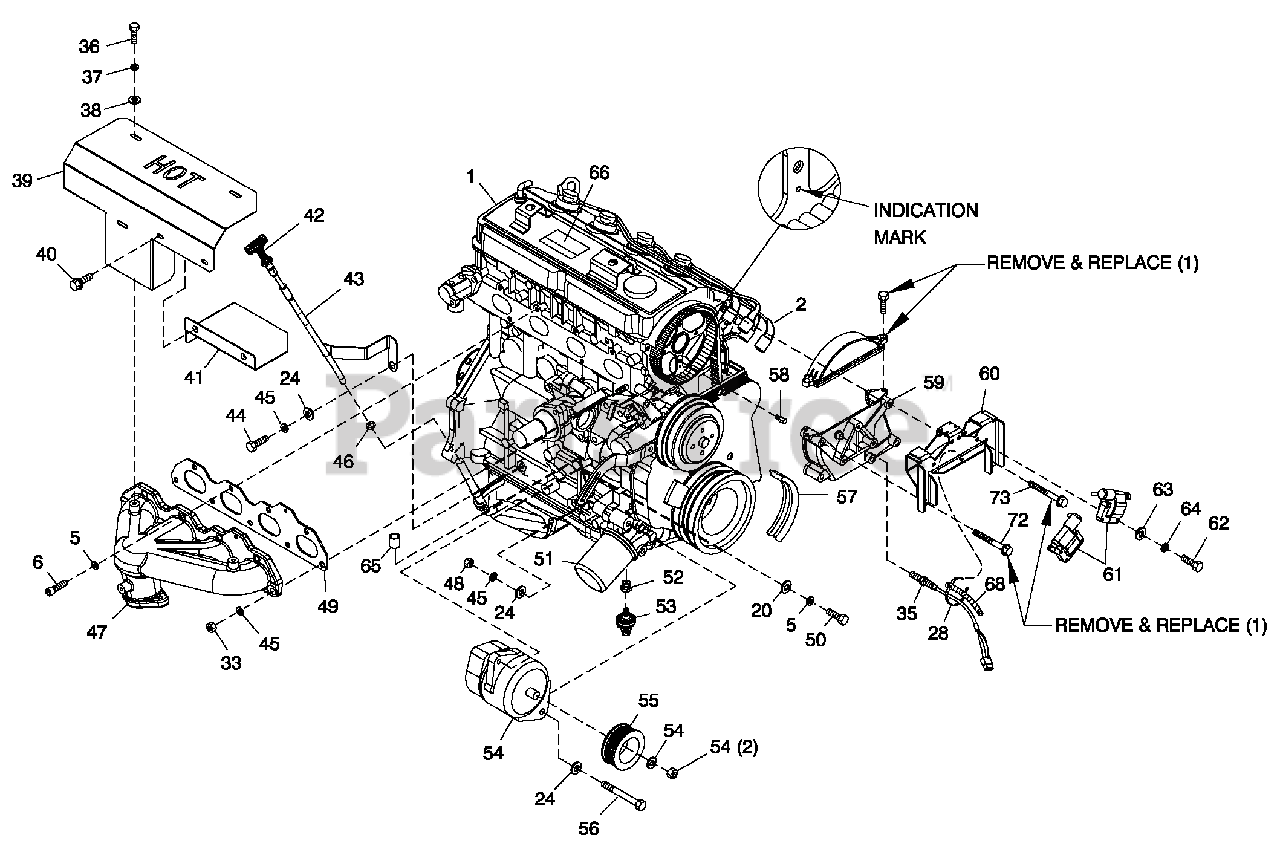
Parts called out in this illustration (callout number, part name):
1	ENGINE 2.4L G2
2	SPARK PLUG WIRE SET 2.4L G2 IG
5	WASHER LOCK M8-5/16
6	SCREW SHC M8-1.25 X 25 C12.9
7	SWITCH HI-TEMP 245D X 3/8 NPT
20	WASHER FLAT 5/16-M8 ZINC
24	WASHER FLAT 3/8-M10 ZINC
28	TIE WRAP UL 7.4"X .19" BLK
33	NUT HEX M10-1.25 G8 YEL CHR
35	ASSY MAGPICKUP(3/8-24 MALE)
36	SCREW HHC M6-1.0 X 12 G8.8
37	WASHER LOCK M6-1/4
38	WASHER FLAT 1/4-M6 ZINC
39	SHIELD EXHAUST
40	SCREW HHTT M6-1.0 X 16 ZYC
41	SHIELD HEAT SML
42	ASSY DIPSTICK W/TEXT GTH-530
43	ASSY DIPSTICK TUBE 2.4 G2
44	SCREW HHC M10-1.25 X 20 C8.8
45	WASHER LOCK M10
47	EXHAUST MANIFOLD G2 (MACHINE)
48	NUT HEX M10-1.5 G8 YEL CHR
49	GASKET EXHAUST MANIFOLD
50	SCREW HHC M8-1.25 X 25 C10.9
52	ADAPTOR 1/8 NPTF TO 1/8 BSPT
53	SWITCH OIL PRESSURE 10 PSI 2 POL
54	ALTERNATOR DC W/OUT PULLEY
55	PULLEY 69 OD DC ALTERNATOR
56	SCREW HHC M10-1.5 X 120 C8.8
57	BELT SERPENTINE 37.0"
58	CAM SENSOR PIN ASSY
59	COVER CAM GEAR G2 REWORKED
60	BRACKET ASM-2.4L COIL G2
61	COIL-2.4L G2 IGNITION
62	SCREW HHM #10-32 X 1-1/4
63	WASHER FLAT #10 ZINC
64	WASHER LOCK #10
65	PLUG TAPER
66	DECAL EMISSION CTRL INFO 2.4L
68	CONDUIT FLEX .25"ID (6"LG)
69	NUT HEX M6 X 1.0 G8 YEL CHR
72	SCREW HHC M8-1.25 X 65 C8.8
73	SCREW HHC M8-1.25 X 70 C8.8
